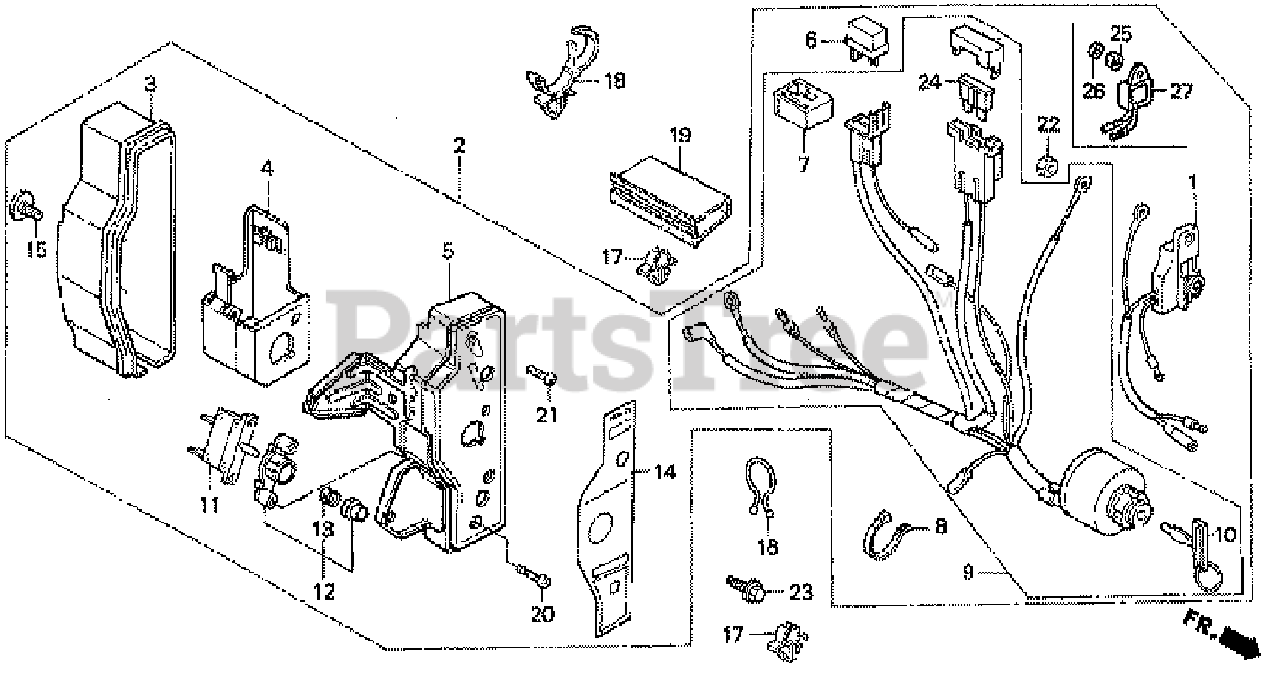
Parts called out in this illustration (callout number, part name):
1	ALERT UNIT, OIL
2	BOX ASSY., CONTROL *R8* (EXTERNAL-ALERT) (BRIGHT RED)
3	CASE, CONTROL
4	BRACKET, CASE MOUNTING
5	PANEL, CONTROL *R8* (BRIGHT RED)
6	RECTIFIER ASSY., SILICON (STANLEY)
7	SUSPENSION, CONNECTOR
8	BAND
9	SWITCH ASSY., COMBINATION
10	KEY
11	PROTECTOR, CIRCUIT (1.0A)
12	LENS ASSY., PROTECTOR
13	SPRING, COIL
14	PANEL, CONTROL BOX (EXTERNAL)
14	PANEL, CONTROL BOX (EXTERNAL-ALERT)
15	SCREW, SPECIAL (6X12)
16	CLIP, PURSE LOCK
17	CLIP, CORD
18	STRAP, WIRE HARNESS (25MM) (BLACK)
19	TUBE, FASTENER (30)
20	SCREW, PAN (3X12)
21	SCREW, PAN (4X12)
22	NUT, HEX. (4MM) (NOT AVAILABLE)
23	BOLT, FLANGE (6X10)
24	FUSE, BLADE (5A)
25	WASHER, PLAIN (4MM)
26	WASHER, SPRING (4MM)
27	ALERT UNIT, OIL
